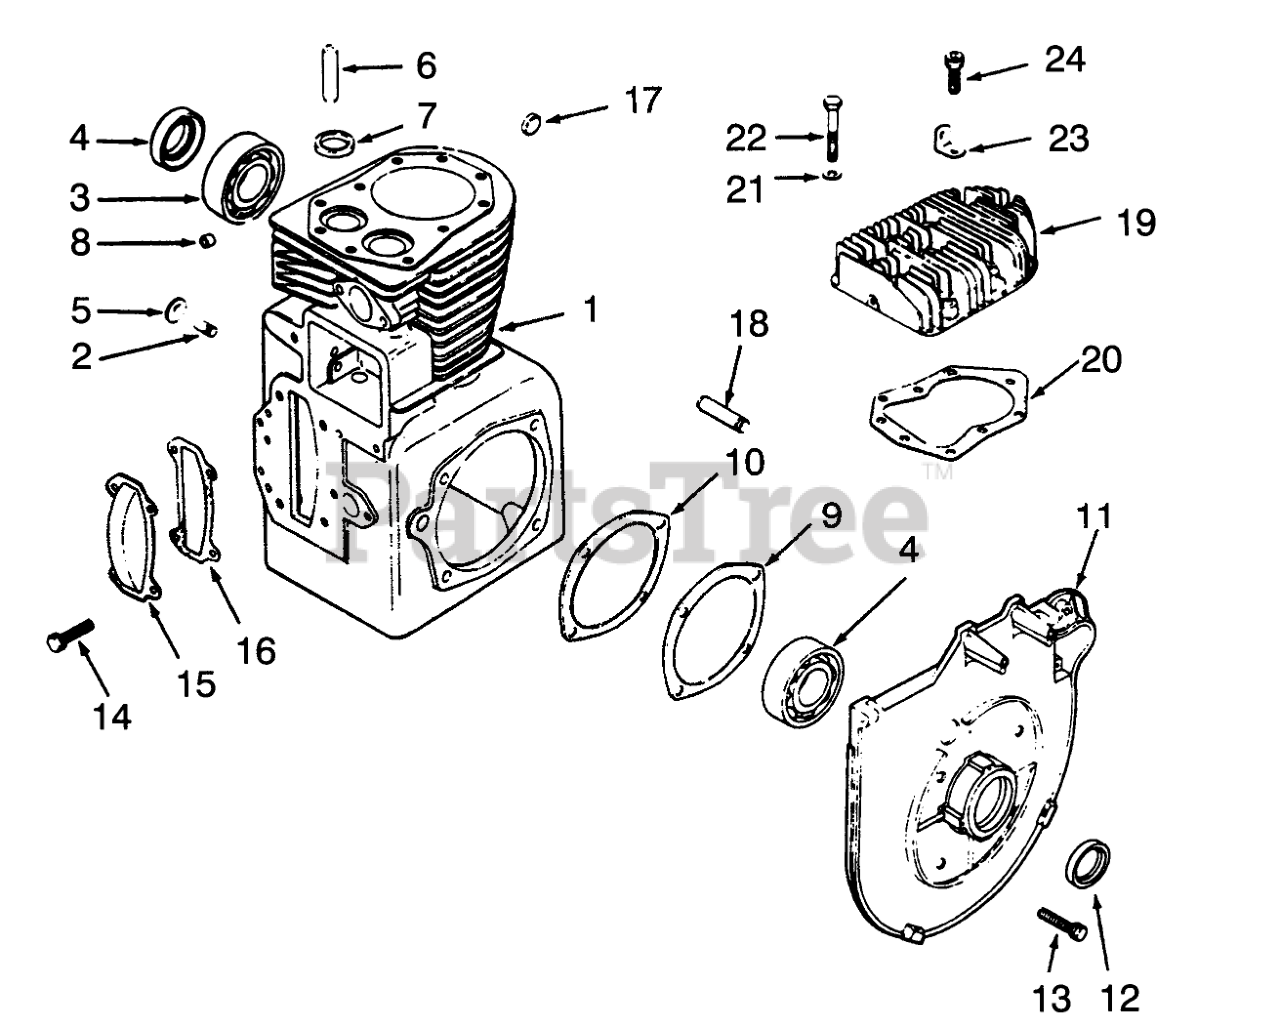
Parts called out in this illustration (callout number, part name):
1	Block-Cylinder Service With Short Block (Includes Crankshaft)
2	Governor Gear Shaft
3	Ball Bearing
6	Guide-Valve
7	Exhaust Valve Insert
8	Bearing
9	Gasket
10	Gasket
11	Bearing Plate
13	Screw
14	Screw
15	Cover
16	Gasket
18	Shaft-Balance Gear
19	Cylinder Head
20	Gasket
21	Washer
22	Screw
23	Lifting Strap
24	Screw
